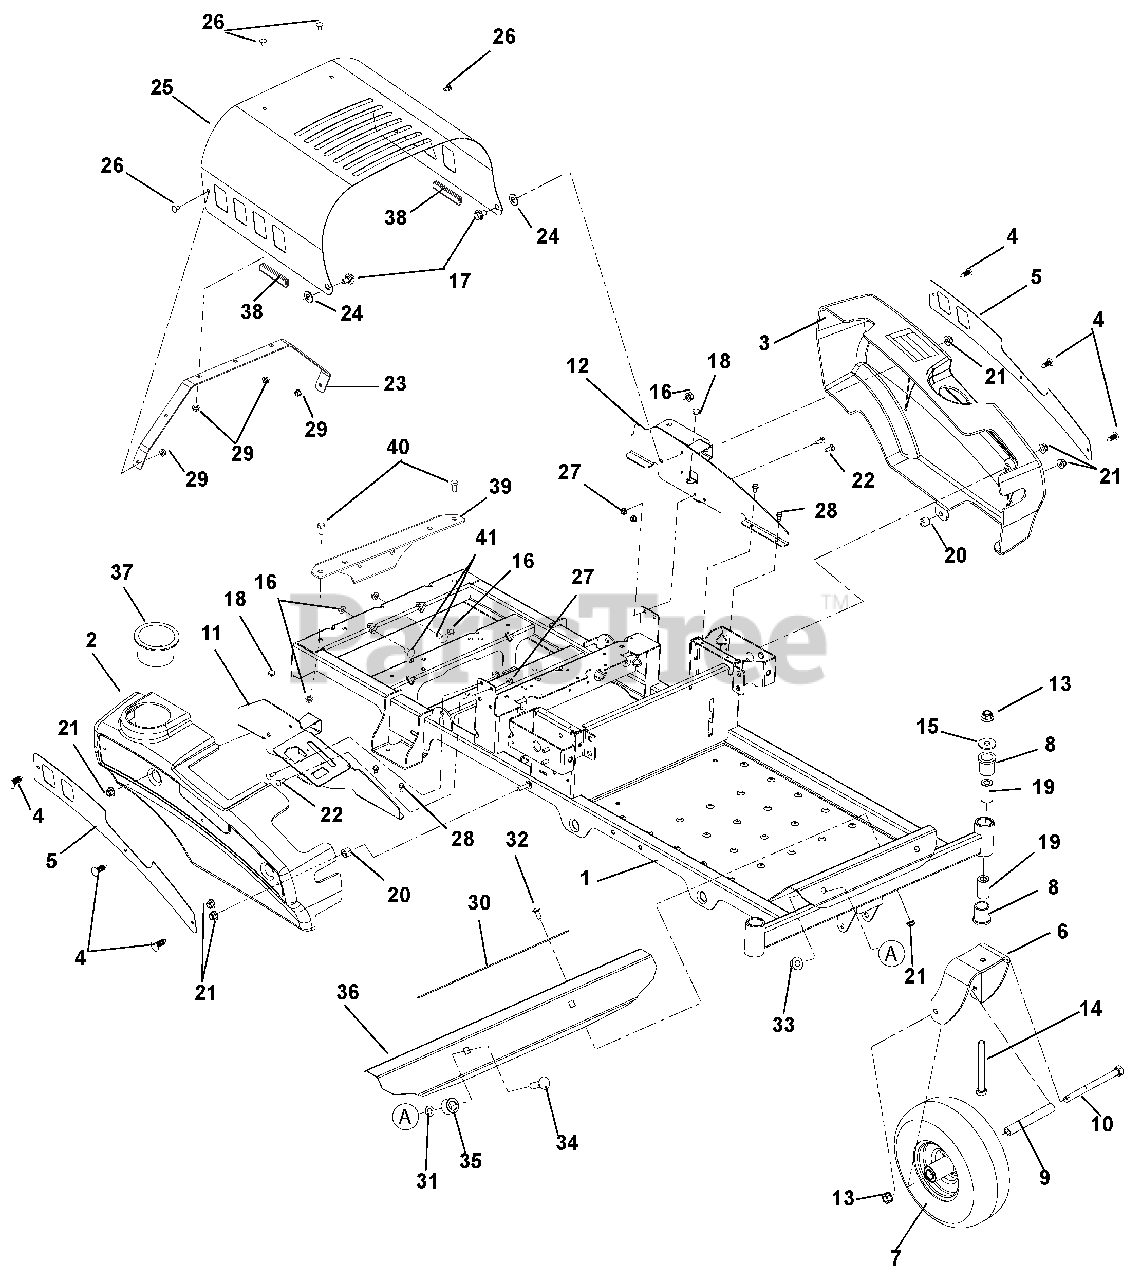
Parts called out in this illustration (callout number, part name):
1	WMT, FRAME ZOOM/ZT
2	FENDER, RH
3	FENDER, LH
4	RIVET, .25 NYLON PANEL
5	PLATE, FENDER
6	WMT, CASTER FORK
7	TIRE/WHL ASM, FRONT
8	BSHG-FLG 1.00X1.25X1.50X1.50
9	SPACER, ROLLED WHEEL
10	@BLT-HEX .50-13X6.50 GR5 YWZC
11	WLDMT, RH FENDER MOUNT
12	WLDMT, LH FENDER MOUNT
13	@NUT-LK-TOP-FLG .50-13 YWZC
14	@BLT-HEX .50-13X5.00 GR5 YWZC
15	WSHR-FL-STL.511X1.441X.125 YWZ
16	@NUT-LK-TOP-FLG .38-16 YWZC
17	BOLT-SHLDR .375-16X.150
18	BUMPER GROMMET
19	SPACER, CASTER .50X1.00X1.84
20	BSHG-SLV .391X.688X.52 PM
21	@NUT-LK-NYL-FLG .31-18 YWZC
22	@BLT-RDHDSQNK .25-20X.75 G5YZ
23	BRACE, HOOD
24	WSHR-FL-NYL .518X1.000X.080
25	HOOD, ZOOM
26	@BLT-RDHDSQNK .25-20X.50 G5YZ
27	@NUT-LK-NYL-FLG .25-20 YWZC
28	@SCR-TAP .25-20X.50 HWH TR YWZ
29	@NUT-LK-TOP-FLG .25-20 YWZC
30	GRIP, ADHESIVE (1" X 16" BLK)
31	NUT-PUSH, .50
32	@BLT-RDHDSQNK .31-18X.75 G5YZ
33	@NUT-LK-NYL-FLG .50-13 YWZC
34	@BLT-RDHDSQNK .50-13X1.75 G5YZ
35	TUBE, UPPER CONTROL PIVOT
36	FOOTREST
37	CUPHOLDER, SNAP-IN 3.75OD
38	EDGING, CLUTCH PADDLE - 2.00"
39	PLATE, BBZ HITCH KIT PLATE
40	@BLT-HEX .38-16X.75 GR5 YWZC
41	@BLT-RDHDSQNK .38-16X.75 G5YZ
